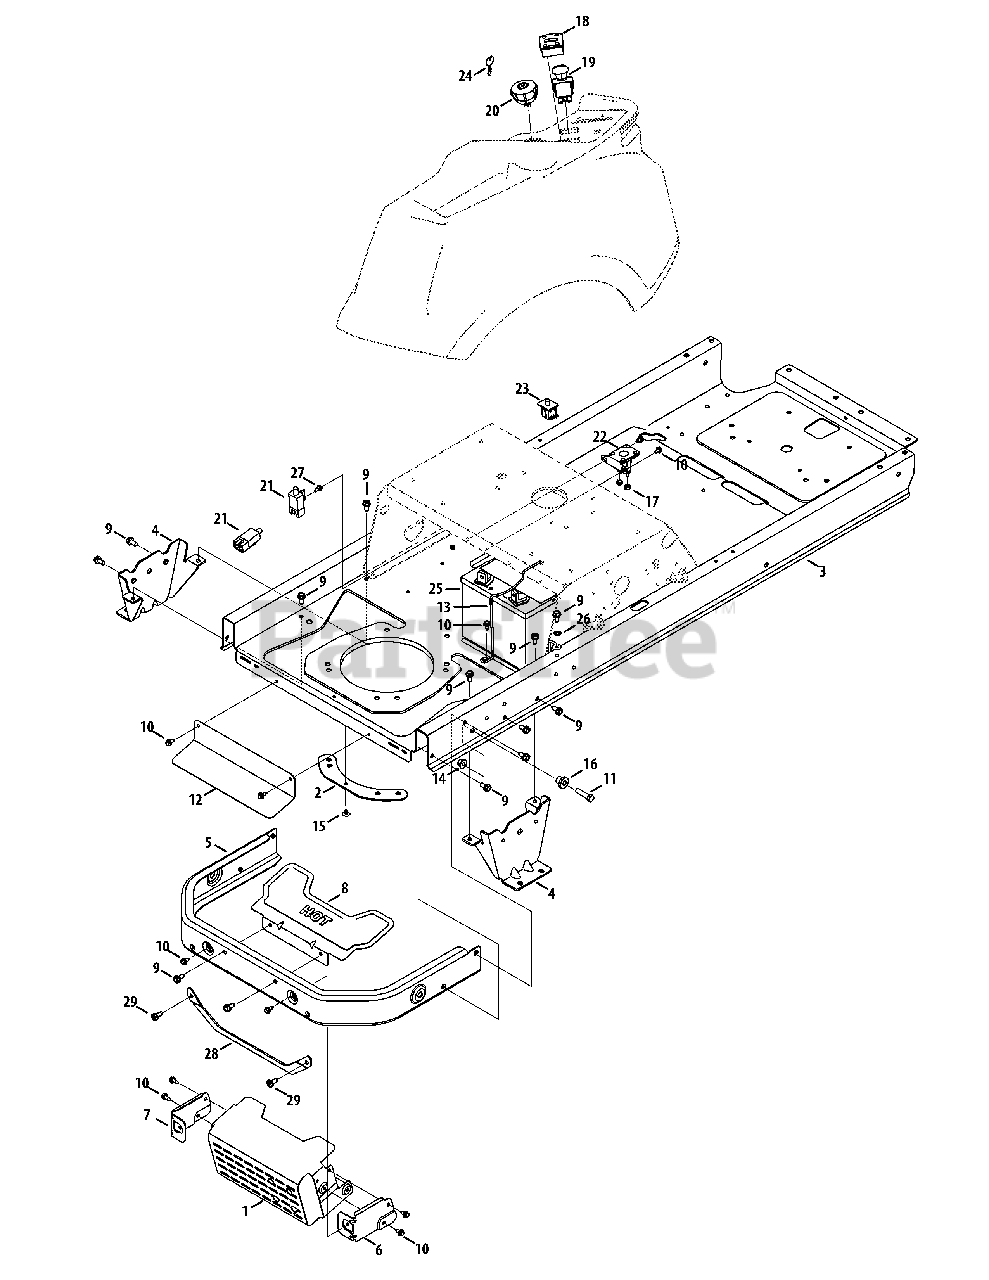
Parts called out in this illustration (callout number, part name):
1	Muffler Shield Assembly
2	Retainer Plate
3	Frame Assembly
4	TRANSMISSION MOUNTING BRACKET
5	Rear Bumper
6	Muffler Mounting Shield Bracket, RH
7	Muffler Mounting Shield Bracket, LH
8	Muffler Shield
9	SCREW 5/16-18 x .750
10	Hex Washer Screw, 1/4-20 x .625
11	Hex Screw, 3/8-16 x 1.25
12	Lower Heat Shield
13	Battery Rod
14	Flange Lock Nut, 3/8-16
15	Clip, .250 Dia. x .500 LG
16	Shoulder Spacer, .38 x 1.0 x .70
17	Flange Lock Nut, 1/4-20
18	Hour Meter/Service Minder
19	Electric PTO Switch
20	Key Switch
21	Interlock Switch
22	Solenoid
23	Seat Switch
24	Key, Assembly
25	Battery
26	Lock Washer, 5/16
27	Shoulder Screw, #10-32 x .500
28	Rear Muffler Shield Bracket
29	Screw, Self-Tapping, 5/16-18, 0.750
